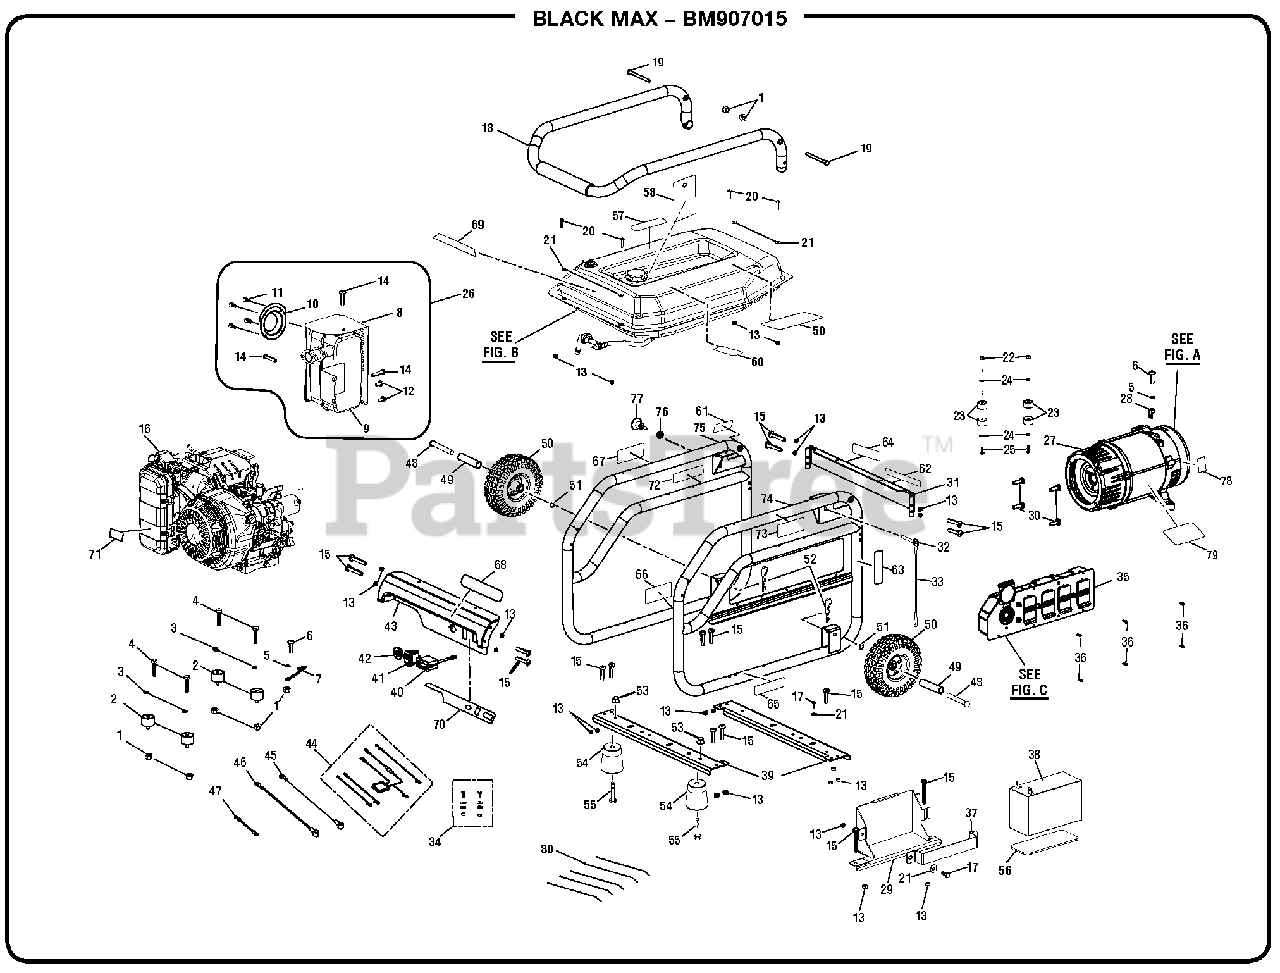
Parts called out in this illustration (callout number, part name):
1	Lock Nut (M8 x 1.25 in.)
3	Lock Washer (OD14.8 x ID8.5 x 1t)
4	Bolt (M8 x 35 mm, Hex Hd.)
5	Star Washer (M8)
6	Bolt (M8 x 15 mm, Hex Hd.)
7	Ground Wire Assembly
8	Heat Shield
9	Muffler w/Brackets
10	Spark Arrestor
11	Screw (8-32 x 3/8 in., Pan Hd.)
12	Bolt (5/16-24 x 0.6 in., Hex Hd.)
13	Lock Nut (M6)
14	Bolt (M6 x 9 mm, Hex Hd.)
15	Screw (M6 x 50 mm, T30 Torx Hd.)
17	Bolt (M6 x 16 mm, Hex Hd.)
18	Handle Assembly
19	Handle Pivot Bolt (M8 x 98 mm, Flat Hd.)
20	Bolt (M6 x 25 mm, T30 Torx Hd.)
21	Washer (M6)
22	Lock Nut (M4)
23	Rubber Bumper
24	Washer (OD9 x ID4.3 x 1t)
25	Screw (M4 x 12 mm, Button Hd.)
26	Muffler Assembly (Inc. Key Nos. 8-15)
27	Generator Head (See Figure A)
28	Ground Lug
29	Battery Tray
30	Bolt (3/8-16 x 1 in., Hex Hd.)
31	Fuel Tank Support (Back)
32	Handle Lock Pin
34	Fastener Kit
35	Control Panel Assembly (See Figure C)
36	Screw (6-20 x 3/8 in., Pan Hd.)
37	Battery Bracket
38	Battery
39	Frame Crossbar
40	Hour Meter
41	Engine Switch
42	Fuel Valve
43	Fuel Tank Support (Front)
44	Wiring Harness
45	Battery Cable (Black)
46	Battery Cable (Red)
47	Bonding Wire
48	Axle (M10 x 99 mm, Pan Hd.)
50	Wheel (10 in. x 3 in.)
51	Washer (OD19.75 x ID10.5 x 1t)
52	Hitch Pin
53	Lock Nut (M8 x 1.25)
54	Rubber Foot
55	Bolt (M8 x 45 mm, Hex Hd.)
57	CPSC Label
58	Warning Hangtag
59	Danger Icon Label
60	E85 Label
61	Handle Release Label
62	Ground Warning Label
63	Lock Pin Label
64	Inquiries Label
65	Lubricant Label
66	Combustion Label
67	Fire Distance Label
68	Logo Label
69	Black Max Label
70	Start Label
71	Electric Start Label
72	Hot Surface Label
73	Fire Danger Label
74	Frame (Right)
75	Frame (Left)
76	Hex Jam Nut (1/2-20)
77	Handle Release Pin
78	Ground Label
79	Data Label
80	Zip Tie (5-1/2 in.)
